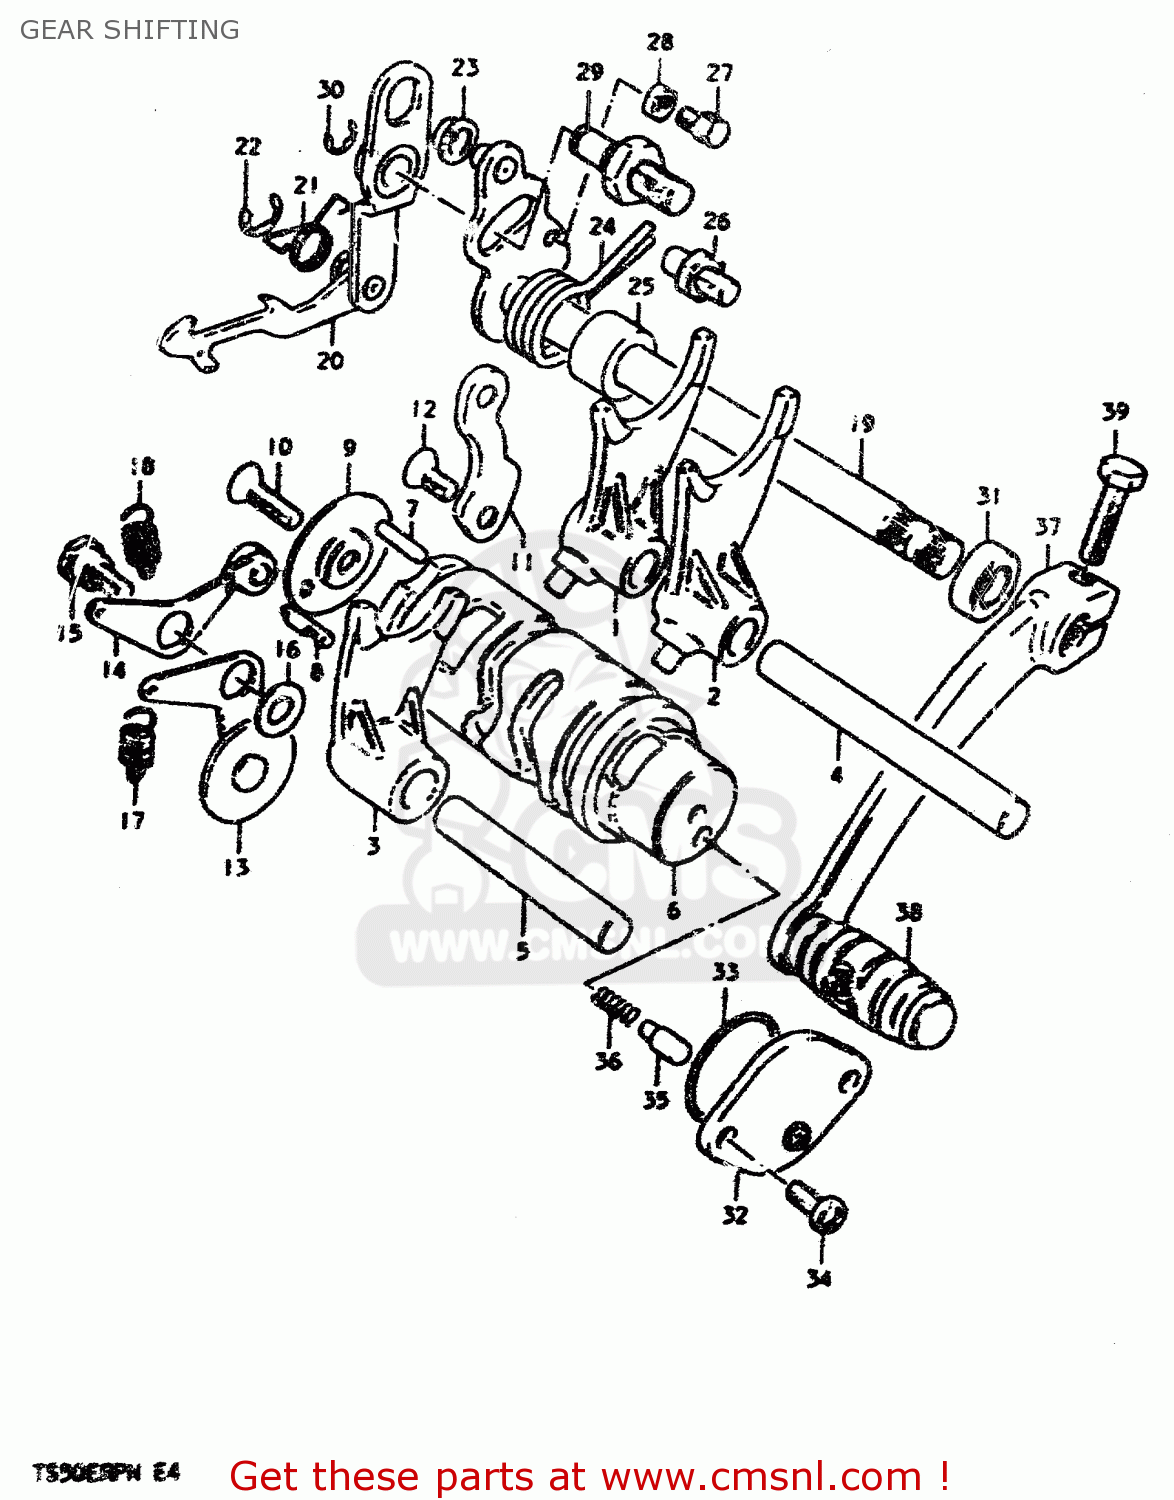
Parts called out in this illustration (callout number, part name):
1	FORK,GEAR SHIFT NO.1
2	FORK,GEAR SHIFT NO.2
3	FORK,GEAR SHIFT NO.2
4	SHAFT,GEAR SHIFT FORK
5	SHAFT,GEAR SHIFT FORK
6	CAM,GEAR SHIFT
7	PIN(4X15.8)
8	PIN
9	RETAINER,GEAR SHIFT CAM DR PIN
10	SCREW
11	GUIDE,GEAR SHIFT CAM
12	SCREW
13	STOPPER,GEAR SHIFT CAM
14	STOPPER,GEAR SHIFT CAM NEUTRAL
15	BOLT(6X18.3)
16	WASHER
17	SPRING
18	SPRING
19	SHAFT, GEAR SHIFTING
20	PAWL,GEAR SHIFTING
21	SPRING
22	E RING
23	SPACER(7X10X5)
24	SPRING
25	SPACER(12X20X15.3)
26	STOPPER,GEAR SHIFT CAM
27	BOLT,GEAR SHAFT RETURN SPR SET
28	NUT 6MM
29	STOPPER,GEAR SHIFT CAM
30	E RING 6MM
31	OIL SEAL
32	BODY,GEAR SHIFT SWITCH
33	O-RING (D:2.4 ID:26.2)
34	SCREW
35	PIN(5X15.5)
36	SPRING
37	LEVER ASSY,GEA
38	RUBBER,GEAR SHIFT PEDAL
39	BOLT
